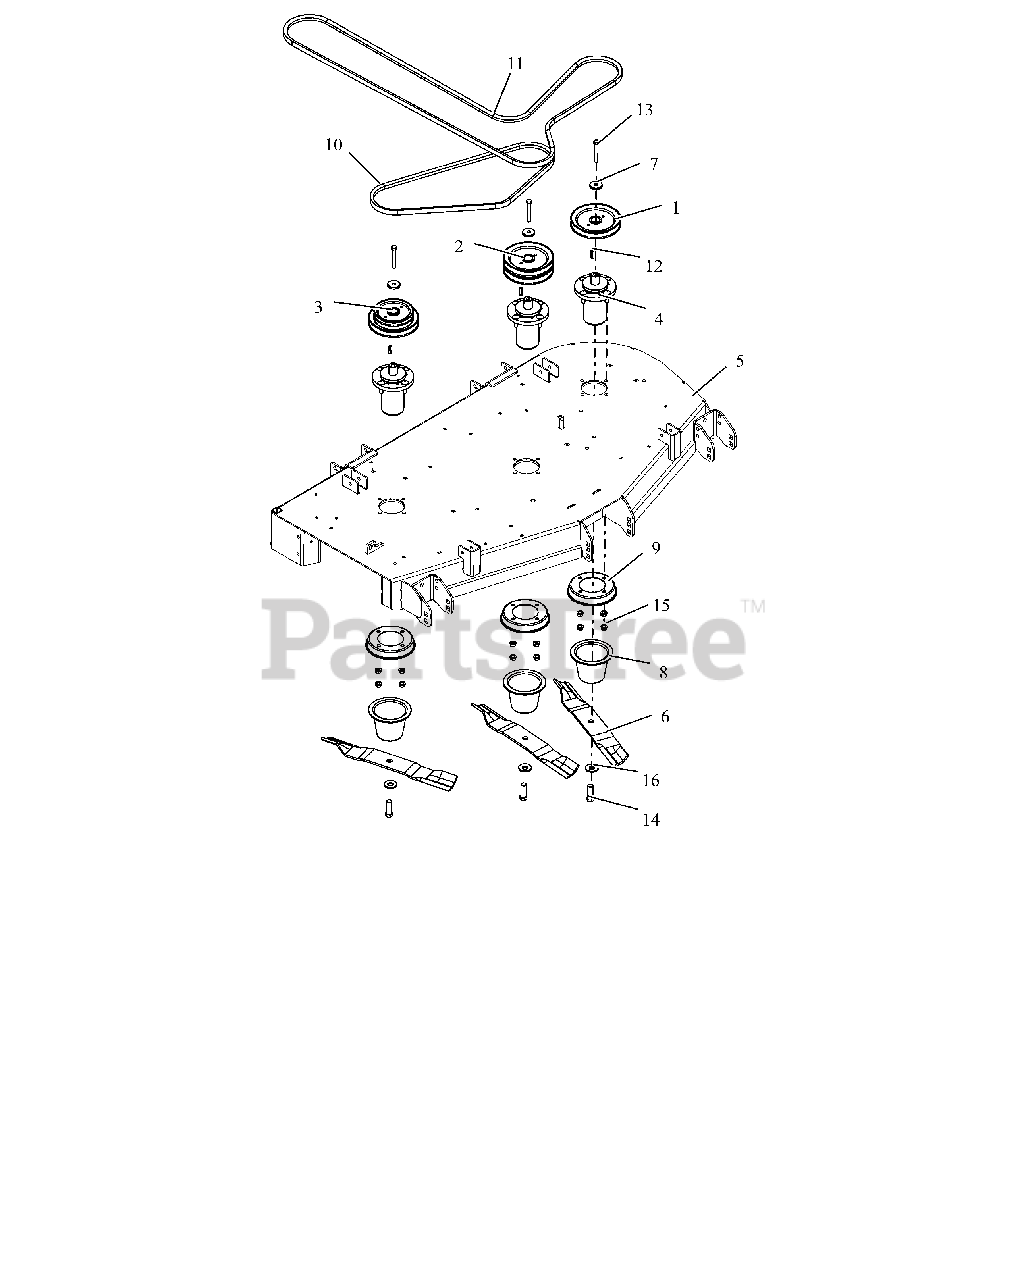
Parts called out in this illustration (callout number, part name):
1	PULLEY, SINGLE-1"ID X 6" OD
2	PULLEY, DOUBLE
3	PULLEY, DBL-1"IDX6.00"&4.75"OD
4	ASM, MAINT FREE ALUM SPINDLE
5	52"SIDE DISCH DECK WMT W/SAFE
6	BLADE, 18.00" MOWER (HI-LIFT)
7	RETAINER, SHEAVE
8	GUARD, SPINDLE LOWER
9	GUARD, SPINDLE TOP
10	V-BELT, B-COGGED
11	V-BELT, HB RAW EDGE EPDM
12	KEY, SQ .25X.25X1.00 RC 40-50
13	BLT, HEX .38-16X2.75 G8 ZCC
14	BLT, HEX .62-18X1.75 G8 ZCC
15	NUT-LK-CTR-FLG .375-16 GF ZCC
16	WSHR-BLVL .669X1.535X.138
